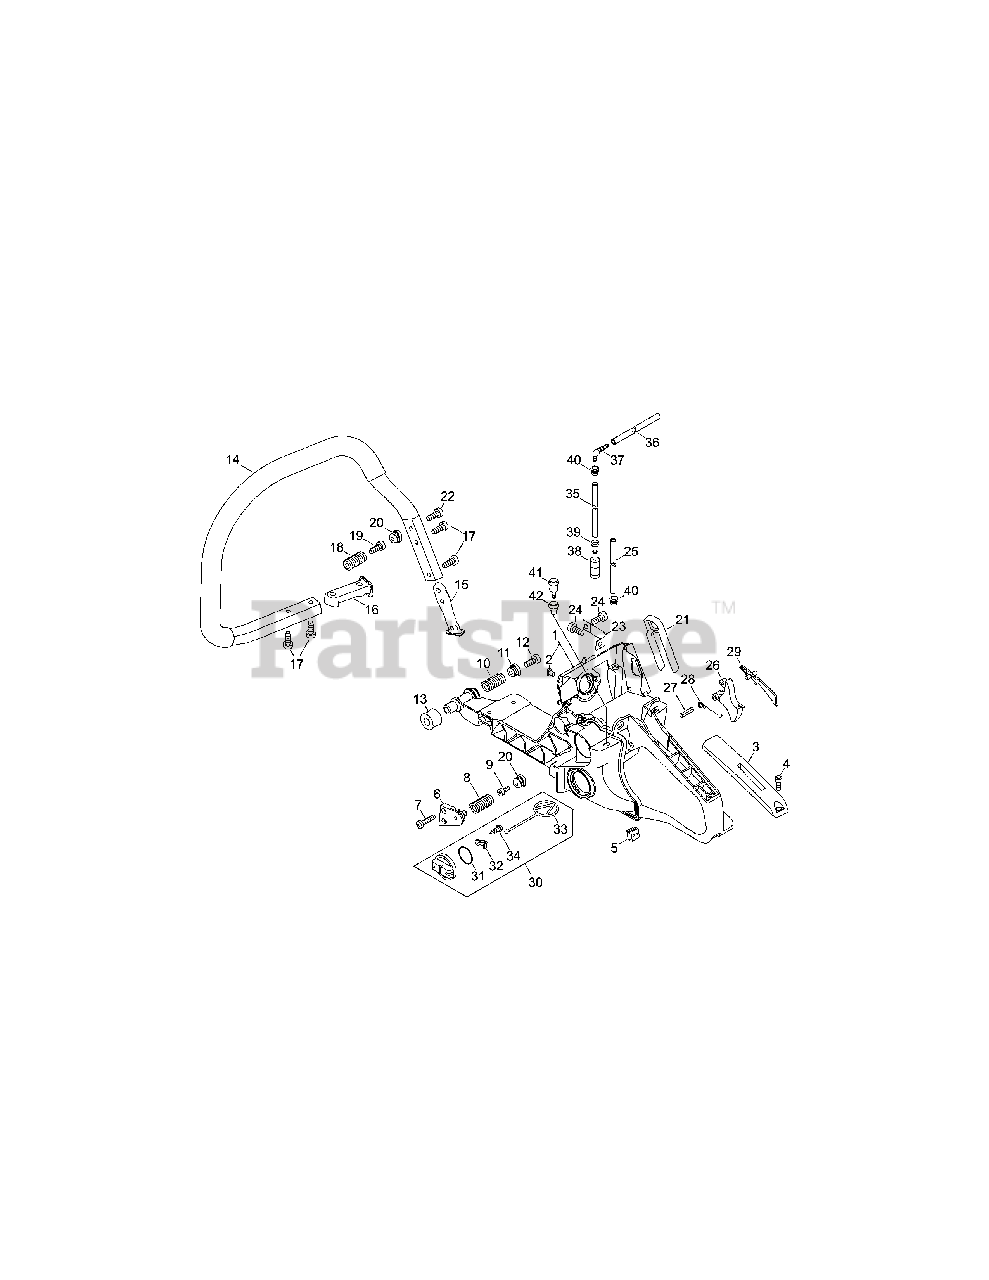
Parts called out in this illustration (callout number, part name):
1	HANDLE, REAR
3	COVER, HANDLE
4	BOLT, TORX 4×12
5	GROMMET, LEAD
6	HOLDER, SPRING
7	BOLT, TORX 5×20
8	SPRING, COMPRESSION Ø17×36.7×2.6
9	BOLT, TORX 5×25
10	SPRING, COMPRESSION Ø20×40×3.3
11	HOLDER, SPRING Ø17
12	BOLT, TORX 6×20
13	CUSHION 10
14	HANDLE, FRONT
15	MOUNT, HANDLE
16	MOUNT, HANDLE
17	BOLT, TORX 5×20
18	SPRING, COMPRESSION Ø17×38.4×2.6
19	BOLT, TORX 5×16
20	HOLDER, SPRING Ø14.4
21	HOLDER, SPRING
22	BOLT, TORX 6×20
23	STRAP, SAFETY
24	BOLT, TORX 5×16
25	PIPE, IMPULSE 3×6(8)×160
26	TRIGGER, THROTTLE
27	PIN, SPRING 4×25 SUS
28	SPRING, TORSION
29	LEVER, THROTTLE LOCKOUT
30	CAP ASSY, FUEL
31	O-RING 29
32	RETAINER, CONNECTOR
33	CONNECTOR, CAP L= 60 MM
34	SCREW, TAPPING 3×8
35	PIPE, FUEL 3×5×120 BLACK
36	PIPE, FUEL 3×6×135L
37	CONNECTOR, PIPE
38	FILTER, FUEL
39	CLIP Ø6
40	GROMMET
41	VENT ASSY
42	GROMMET, VENT
